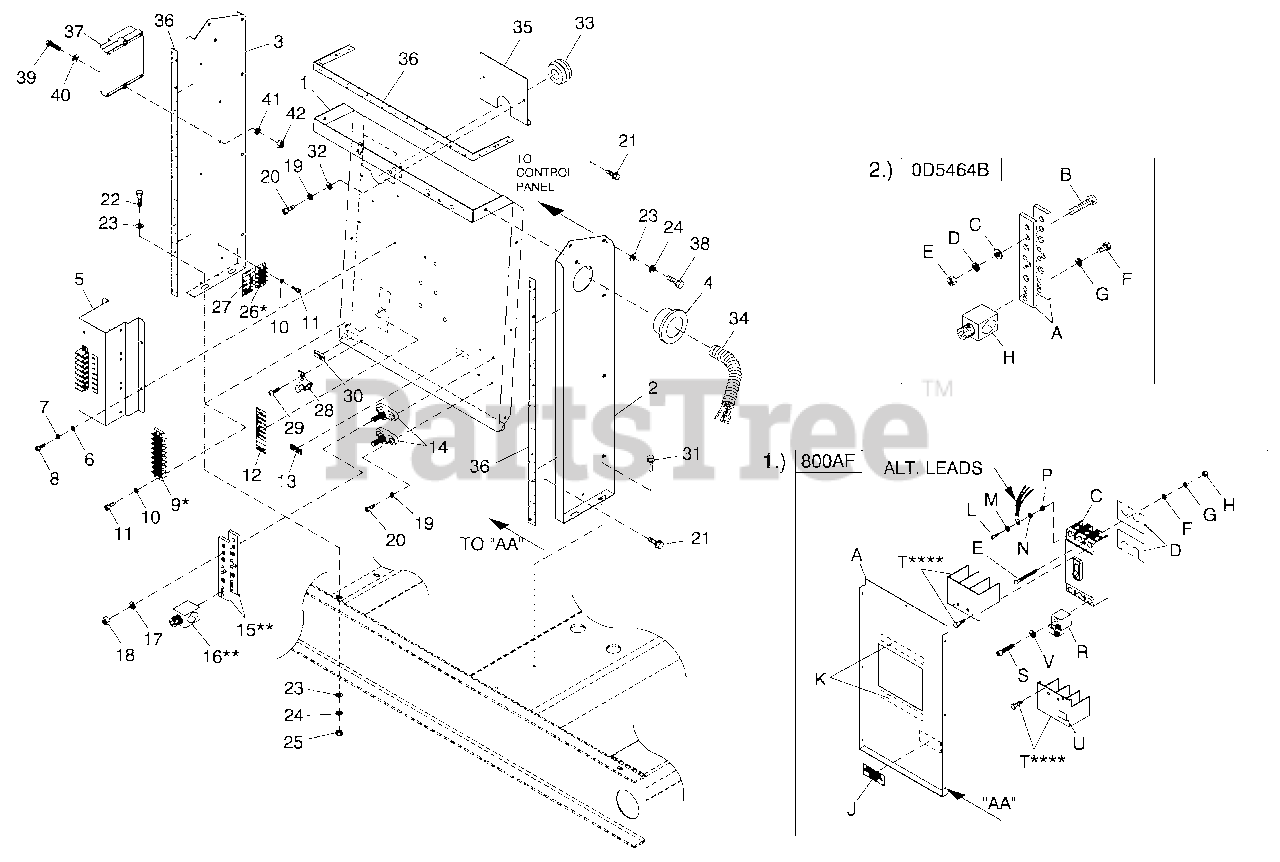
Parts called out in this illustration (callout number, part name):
0G0171A	STAND RH CONTROL CPL C5 2 HOLE
1	PANEL CB CONN BOX
2	STAND RH CONTROL CPL C5
3	STAND LH CONTROL CPL C5
4	BUSHING SNAP SB-2.5-31
5	ASSY PCB INTERFACE 1PH 240V
6	WASHER FLAT M4
7	WASHER LOCK #8-M4
8	SCREW PHTT M4-0.7 X 10 ZYC
9	BLOCK TERM 2 0 A 8 X 6 X 1100V
10	WASHER LOCK #6
11	SCREW PHTT # 6 -3 2X1 /2 ZYC
12	DECAL CPL CUST CONN H CTRL
13	DECAL NEUTRAL
14	JUNCTION BLOCK 3/8-16
15	BUS BAR NEUTRAL BLOCK 390
16	LUG SLDLSS 600/250-1/0 X 1/4-28
17	WASHER LOCK 3/8
18	NUT HEX 3/8-16 STEEL
19	WASHER LOCK M5
20	SCREW PHTT M5-0.8X 16 ZYC
21	SCREW THF M6-1 X 16 N WA Z/JS
22	SCREW HHC M6-1.0X 20 G8.8
23	WASHER FLAT 1/4-M6 ZINC
24	WASHER LOCK M6-1/4
25	NUT HEX M 6X 1.0 G8YEL CHR
26	BLOCK TERM 2 0 A 6 X 3 X 1100V
27	DECAL CUST CONN 120V UTILITY
28	LUG SLDLSS #6-14X 13/64CU
29	SCREW HHTT # 10-32X3/8 CZ
30	DECAL GROUND LUG
31	SCREW HHTT M6-1.0X16ZYC
32	WASHER FLAT M5
33	GROMMET 1.25 X .25 X .75
34	CONDUIT FLEX 2.0" ID
35	PLATE WIRE SNGLGALV
36	TAPE ELEC 1/2 FOAM (AS REQ'D)
37	ASSY PCB HSB CTRL IGN MODULE
38	SCREW HHC M 6-1.0X 16G 8.8
39	SCREW PPHM # 1 0 /32X 2
40	WASHER FLAT #10 ZINC
41	WASHER LOCK #10
42	NUT HEX #10-32 STEEL
A	COVER, CB 803 C5
C	CIRCUIT BREAKERS 800A FRAME
D	INSULCB800AF
E	SCREW RHM 1/4-20X1-1/2
F	WASHER FLAT 1/4-M6 ZINC
G	WASHER LOCK M6-1/4
H	NUT HEX 1/4-20 STEEL
J	DECAL CUSTOMER CONNECT INSIDE
K	TAPE ELEC 1/2 FOAM
L	SCREW SHC M 10-1.50 X 40 G12.9
M	WASHER FLAT 3/8-M10 ZINC
N	WASHER LOCK 3/8
P	NUT HEX M10-1.5G8YEL CHR
R	LUG SLDLSS 3/0-400X3 MCM AL/CU
S	SCREW SHC M6-1.0X 50 G8.8
T	TERM. COVER VITZROTECH 400AF CB
U	DECAL TERMINAL SHOCK HZD BI
V	WASHER LOCK M6-1/4
A	BUS BAR NEUTRAL BLOCK 390
B	SCREW HHC M 8-1.25 X 45 G8.8 FT
C	WASHER FLAT 5/16-M8 ZINC
D	WASHER LOCK M8-5/16
E	NUT HEX M-81.25 G8 YEL CHR
F	SCREW HHC 1/4-28 X 3/4 G5
G	WASHER LOCK 1/4-M6 SS
H	LUG SLDLSS 600/250-1/0 X 1/4-28
